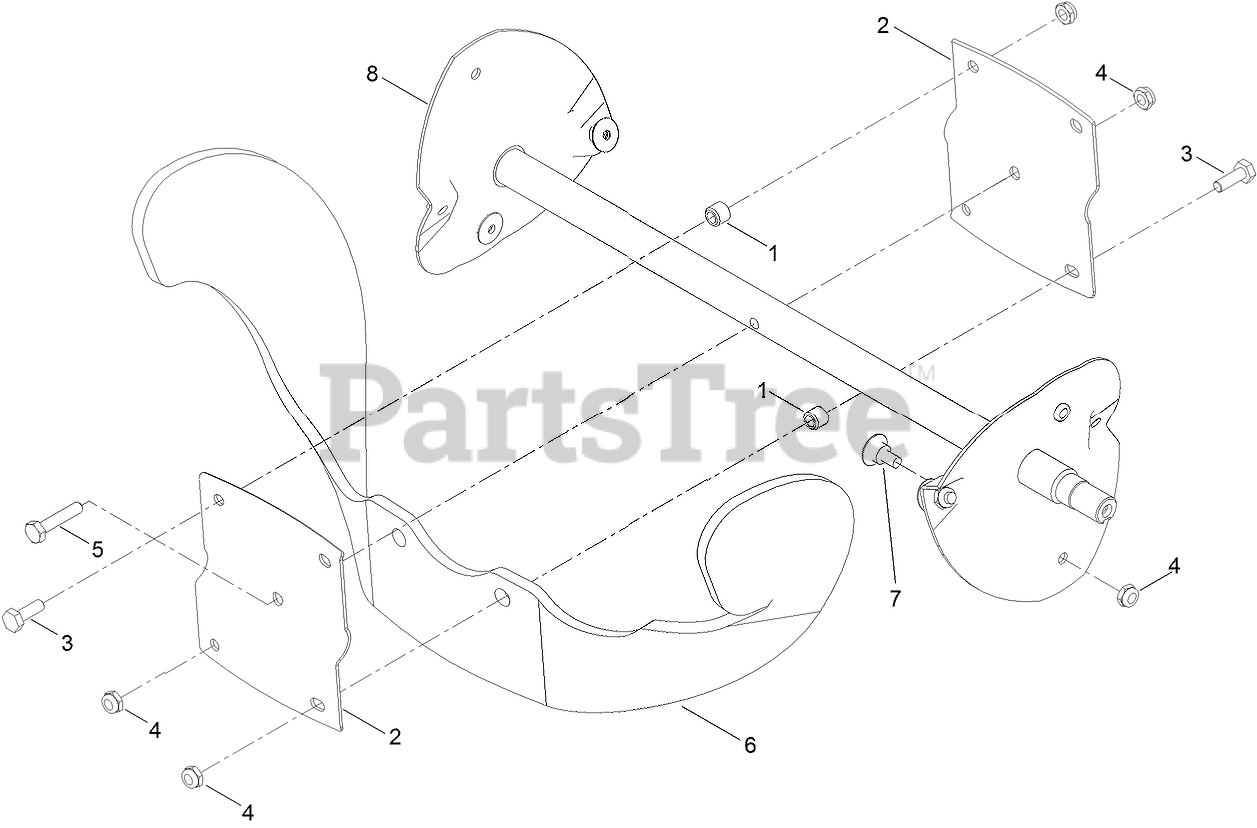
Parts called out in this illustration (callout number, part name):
1	SPACER-BLADE, ROTOR
2	HALF-ROTOR
3	SCREW-HH
4	NUT-LOCK, NI
5	SCREW-HH
6	BLADE-ROTOR
8	ROTOR KIT
